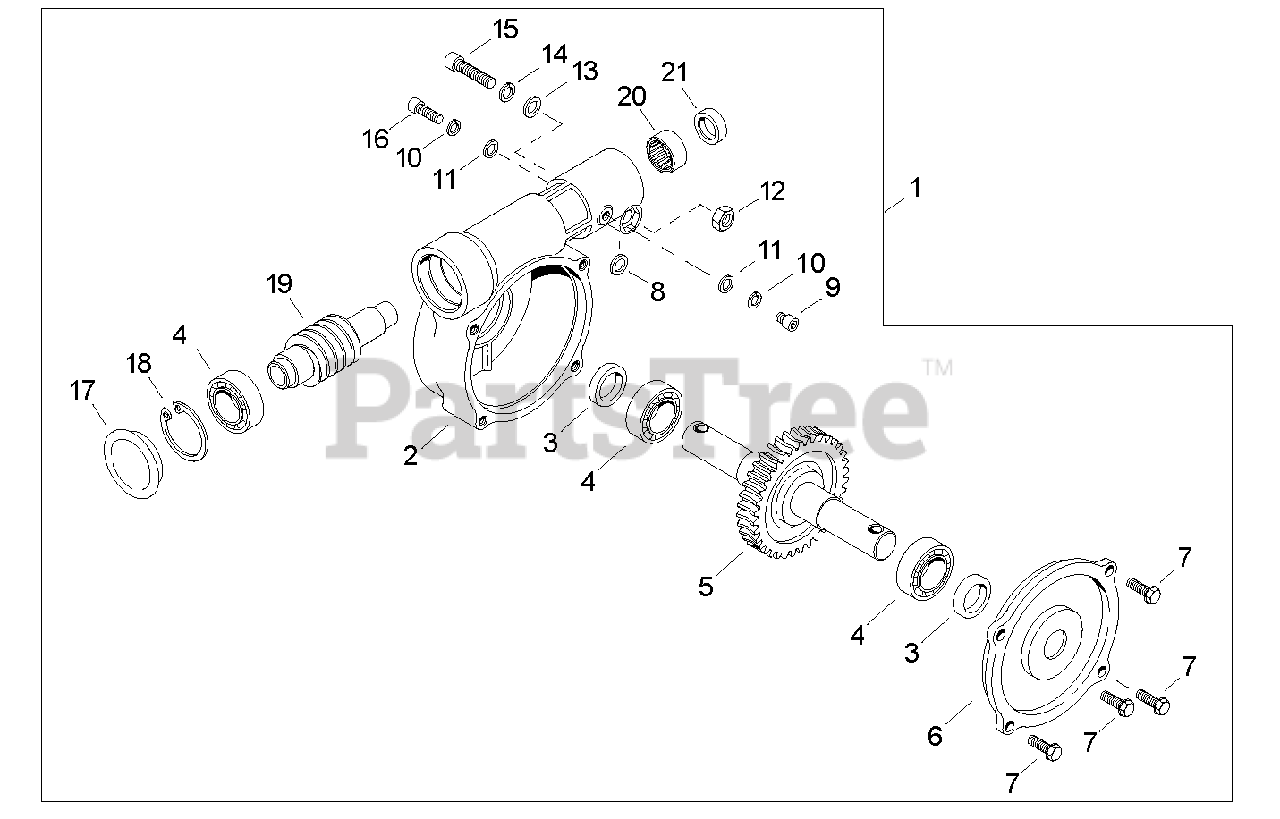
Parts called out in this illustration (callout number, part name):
1	GEAR CASE ASSY
3	SEAL, OUTPUT SEG TC15-24-5-20
4	BEARING, BALL PEER 6002
5	GEAR - DRIVE
7	SCREW SELF-TAPPING 5×16
8	WASHER M6
9	BOLT 5×8×0.80
10	WASHER, SPRING 5
11	WASHER, FLAT 5.5×10×0.8
12	NUT M6
13	WASHER M6
14	WASHER, LOCK M6
15	SCREW, SOCKET HEAD 6×30
16	BOLT 5×12
17	PLUG
18	RING, SNAP 34 MM
20	BEARING, NEEDLE SCE 107 1/2 NF R
21	SEAL, INPUT SCG TC-12-21-6
